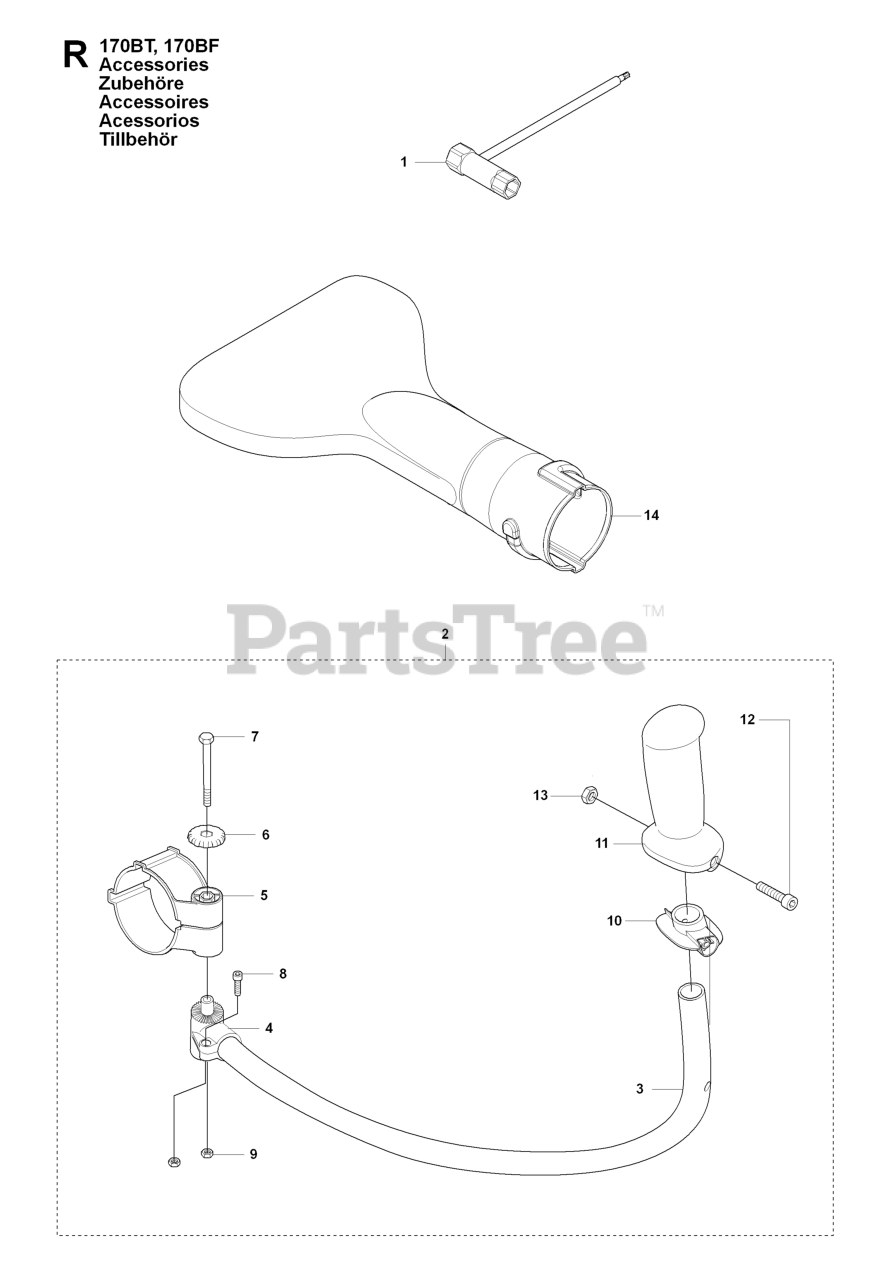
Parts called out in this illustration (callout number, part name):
2	HANDLEBAR ASSY
6	KNOB
8	SCREW MC6S 5X10
9	NUT
13	NUT
14	FLAT NOZZLE
